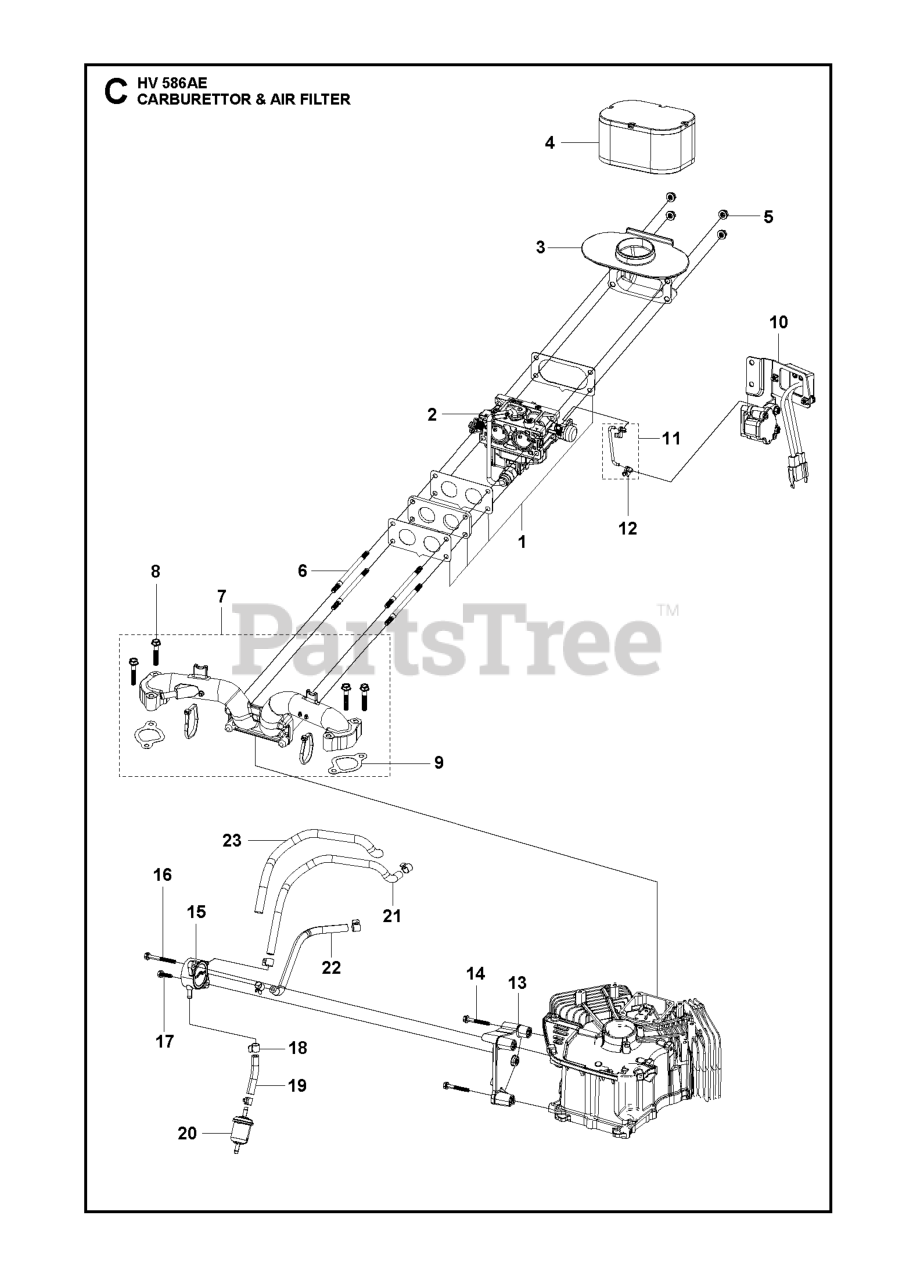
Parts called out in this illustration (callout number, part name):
5	NUT GB/T 6177.1: M6
8	BOLT GB/T 5789: M6 L=35
17	BOLT GB/T 5789: M6 L=25
18	CLIP HOSE CLIP
